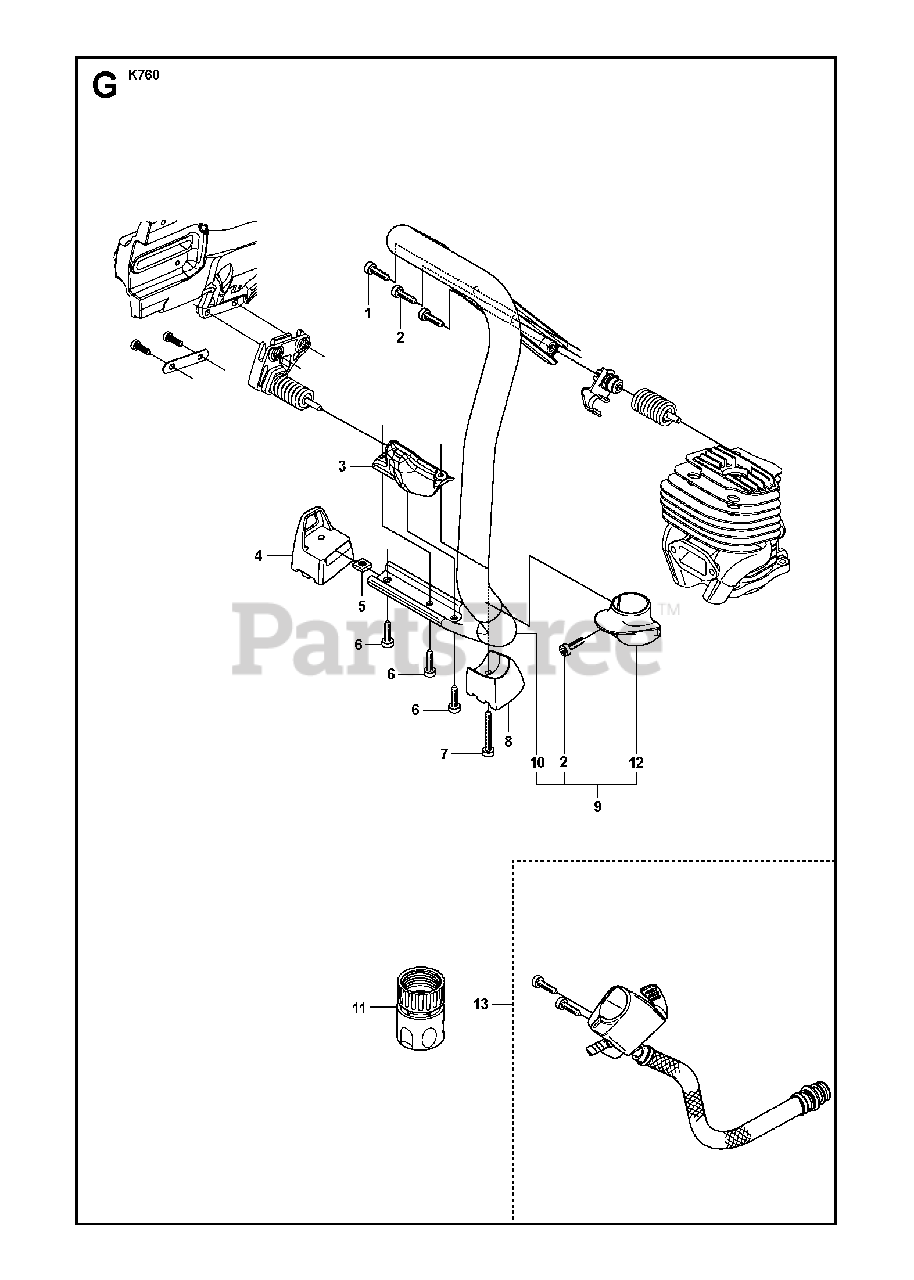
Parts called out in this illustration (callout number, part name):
1	SCREW ITXSCM
2	SCREW ITXSCT
3	SPRING RETAINER
4	GROUND SUPPORT
6	SCREW ITXSCM
7	SCREW ITXSCM
8	GROUND SUPPORT
9	HANDLEIncl. 2, 10 - 11
10	FRONT HANDLE
12	COUPLERUSA, Canada
